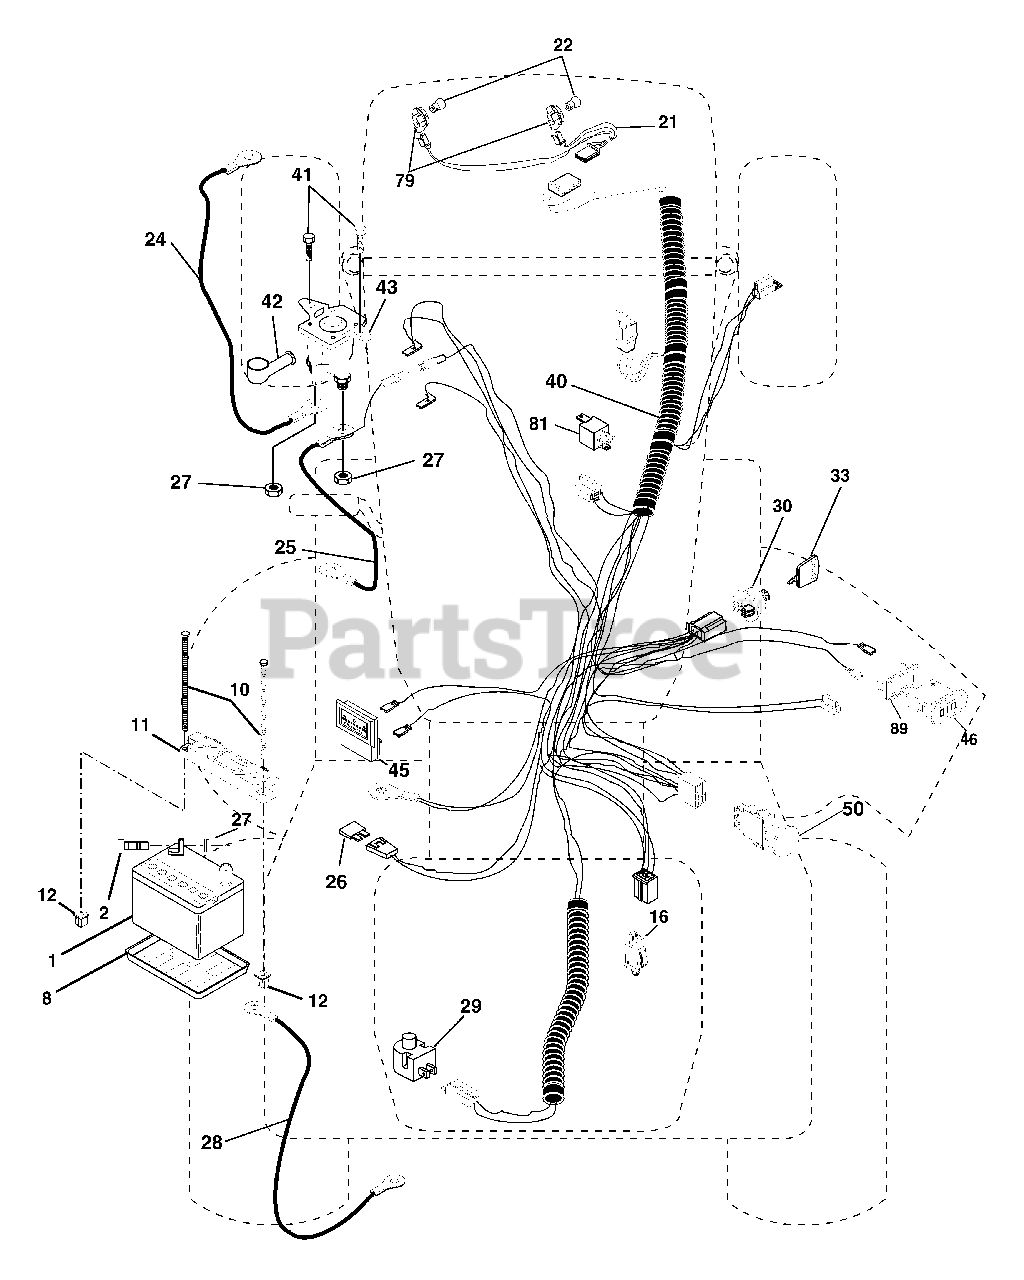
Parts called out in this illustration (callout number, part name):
1	Battery
2	Bolt Hex Head 1/4-20 x 3/4
8	Tray, Battery
10	Bolt, Battery Front 1/4-20 x 7.5 Zinc
11	Holddown Battery Front Mount
12	Nut, Push Nylon 1.4" Battery Front
16	Switch Interlock Push-In
21	Harness Socket Light w/4152J
22	Bulb Light
24	Cable Battery
27	Nut Keps Hex 1/4-20
28	Cable Bolt Ground
29	Switch, Plunger Normal Op Olive
30	Switch, Ign
40	Harness Ign.
41	Screw 1/4-20 x 1/2
42	Cover, Terminal Red
43	Solenoid
46	Hourmeter Snap-In
50	Switch, PTO
79	Bulbholder Asm
81	Relay Asm.
89	Bracket Snap-In Hourmeter
